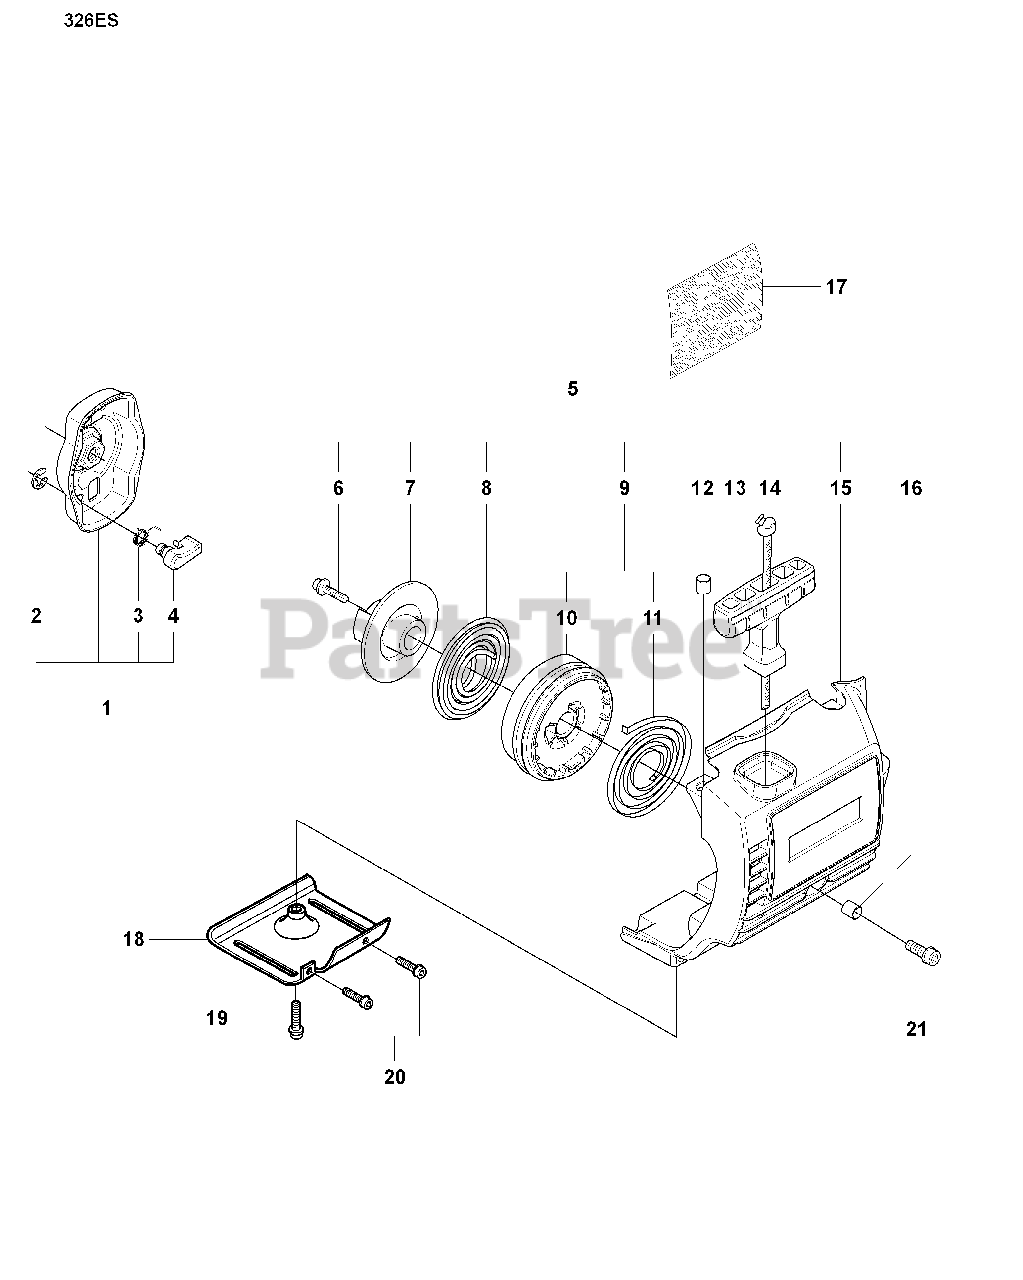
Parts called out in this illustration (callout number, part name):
1	STARTER PAWL BRIDGE
4	STARTER PAWL
5	RP STARTER ASSY
7	WHEEL
8	BALANCING SPRING
9	STARTER PULLEY
10	STARTER PULLEY
12	SPACING SLEEVE
13	STARTER HANDLE
14	STARTER ROPE
15	RP STARTER HOUSING
16	SPACING SLEEVE
19	SCREW
21	SCREW
